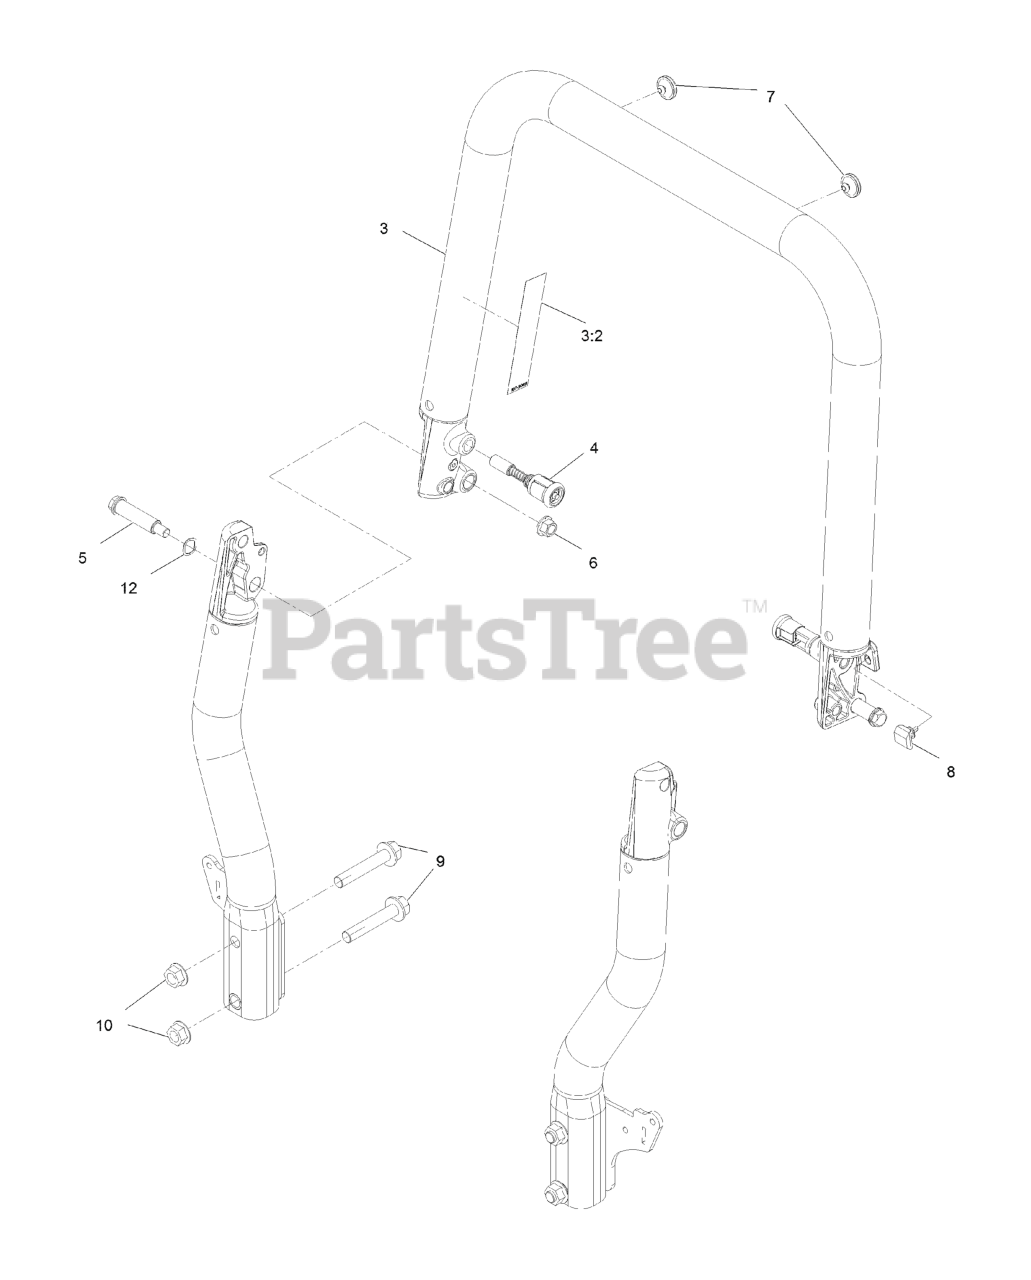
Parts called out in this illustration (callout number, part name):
3	TOP TUBE ASM
3:2	DECAL-WARNING
4	PIN-SPRING
5	BOLT-SHOULDER
6	Nut-Lock 1/2-13
7	BUMPER-ROPS
8	BUMPER-ROPS
9	SCREW-HHF
10	NUT-FLANGE
12	WASHER-WAVE
